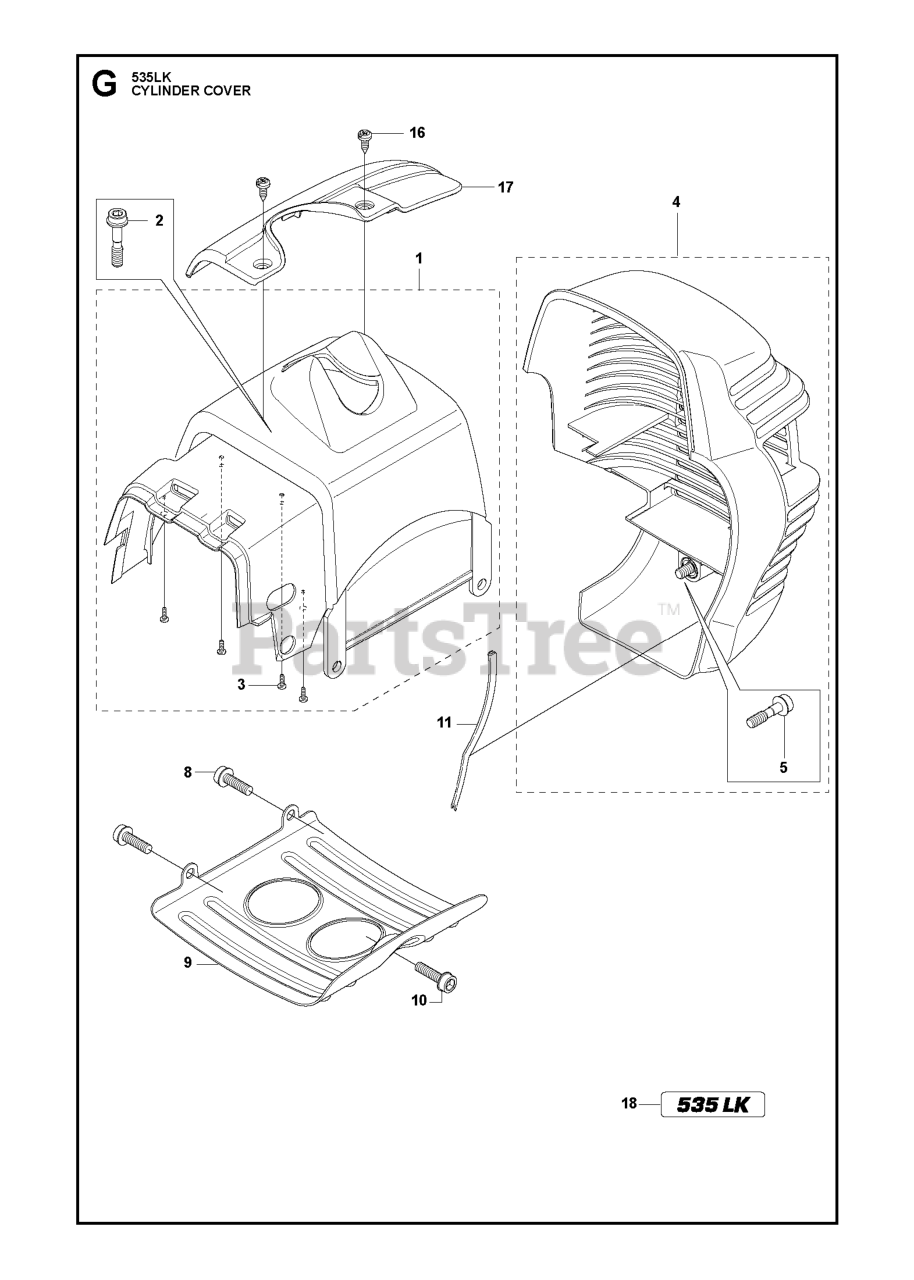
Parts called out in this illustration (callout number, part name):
1	CYLINDER COVER
2	SCREW IHSCFMO
4	HEAT PROTECTOR
5	SCREW IHSCFMO
16	SCREW CCRPANT ST4.2X9.5 DS
17	ARM PROTECTION
